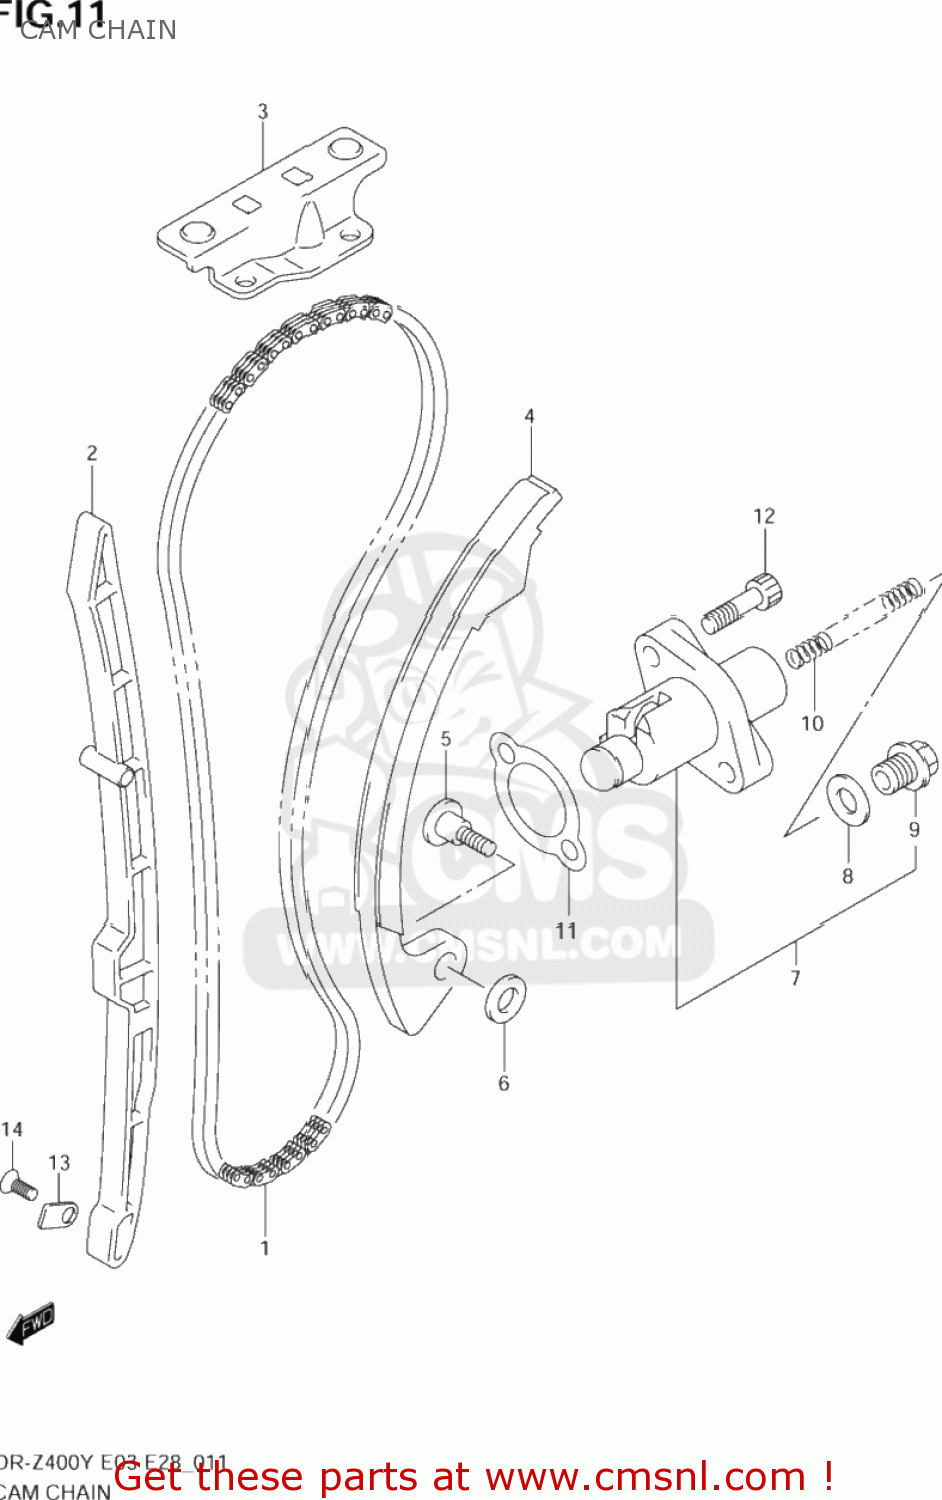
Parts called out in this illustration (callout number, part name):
1	CHAIN COMP,CAMSHAFT DRIVE
2	GUIDE,CAM CHAIN NO.1
3	GUIDE,CAM CHAIN NO.2
4	TENSIONER,CAM CHAIN
5	BOLT,CAM CHAIN TENSIONER
6	WASHER
7	ADJUSTER ASSY,TENSIONER
8	GASKET,TENSIONER ADJUSTER
9	PLUG,FR TENSIONER ADJ
10	SPRING
11	GASKET,TENSIONER ADJUSTER (NAS)
12	BOLT,CL.COVER
13	RETAINER,CAM CHAIN GUIDE NO.1
14	SCREW(6X12)
